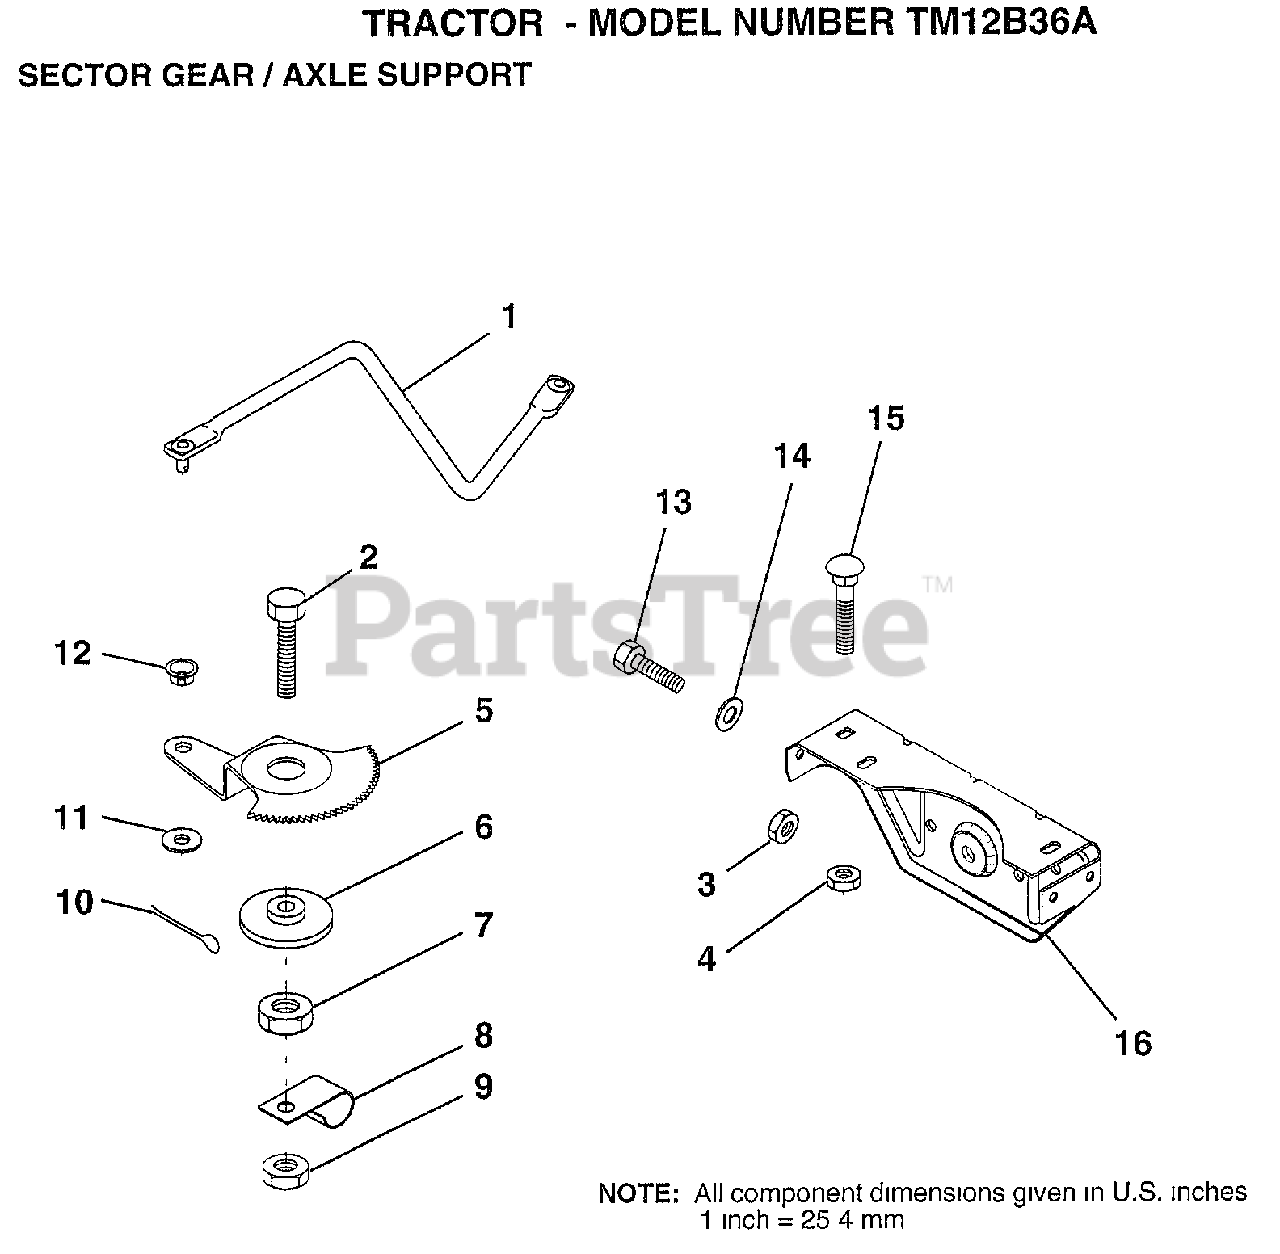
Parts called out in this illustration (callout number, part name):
1	DRAG LINK
2	"BOLT,HEX"
5	GEAR SECTOR
6	BUSHING
7	NUT
8	CLIP INSULATOR
9	NUT LTV
10	COTTER PIN
11	WASHER
12	BUSHING.DRAGLINK
13	BOLT
14	WASHER
15	BOLT
16	SUPT AXLE FRONT
